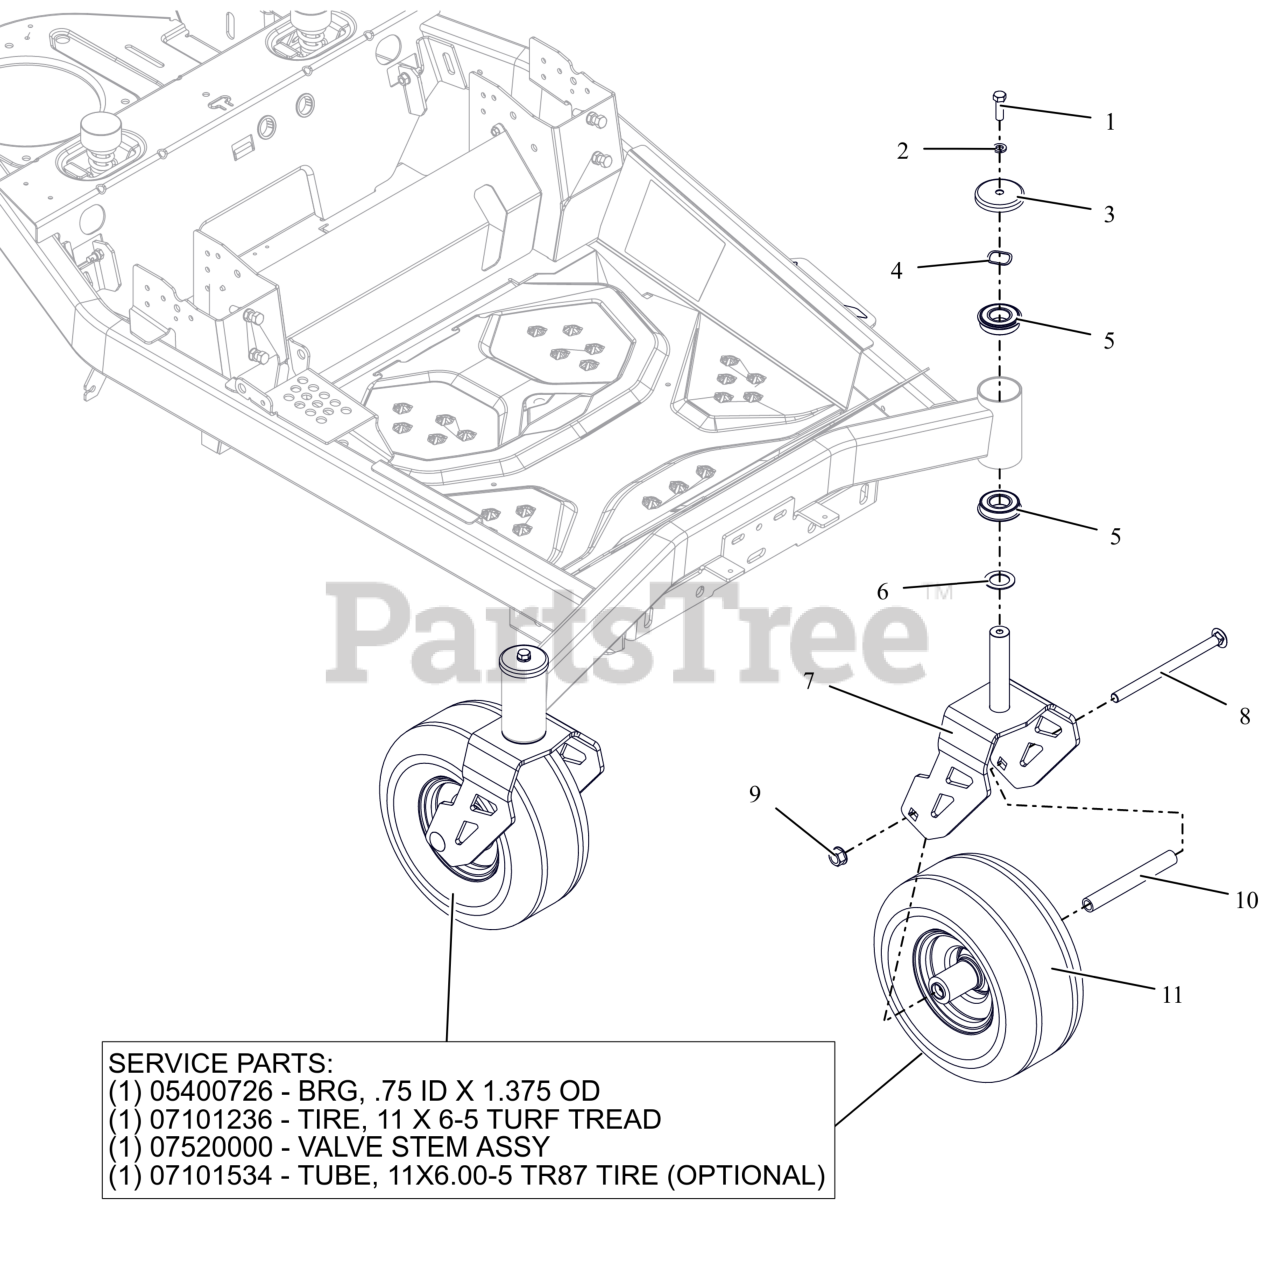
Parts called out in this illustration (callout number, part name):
1	BLT- HEX .38-16X1.25 G5 ZB500
2	WSHR-LK-REG .375X.094 ZB500
3	SHIELD, AXLE BEARING
4	WSHR-WAVE 1.0X1.25X.028 .145FH
5	BEARING, BALL -2.000 OD X 1.000 ID X .5625 W/RING
6	WSHR-HRD-THRS 1.007X1.542X.062
7	WLDMT, CASTER FORK (ORANGE)
8	BLT-RHSN .50-13X7.50 G5 ZCC NS
9	NUT-LK-CTR-FLG .500-13 GG ZCC
10	SPACER, FRONT WHEEL (WIDE 6.0)
11	TIRE/WHEEL ASSY 11X6-5
11	BRG, .75 ID X 1.375 OD
11	LAWN TIRE FRONT, 11/6.00-5 SMOOTH
11	VALVE STEM ASS'Y
11	TUBE- 11X6.00-5 TR87 TIRE
